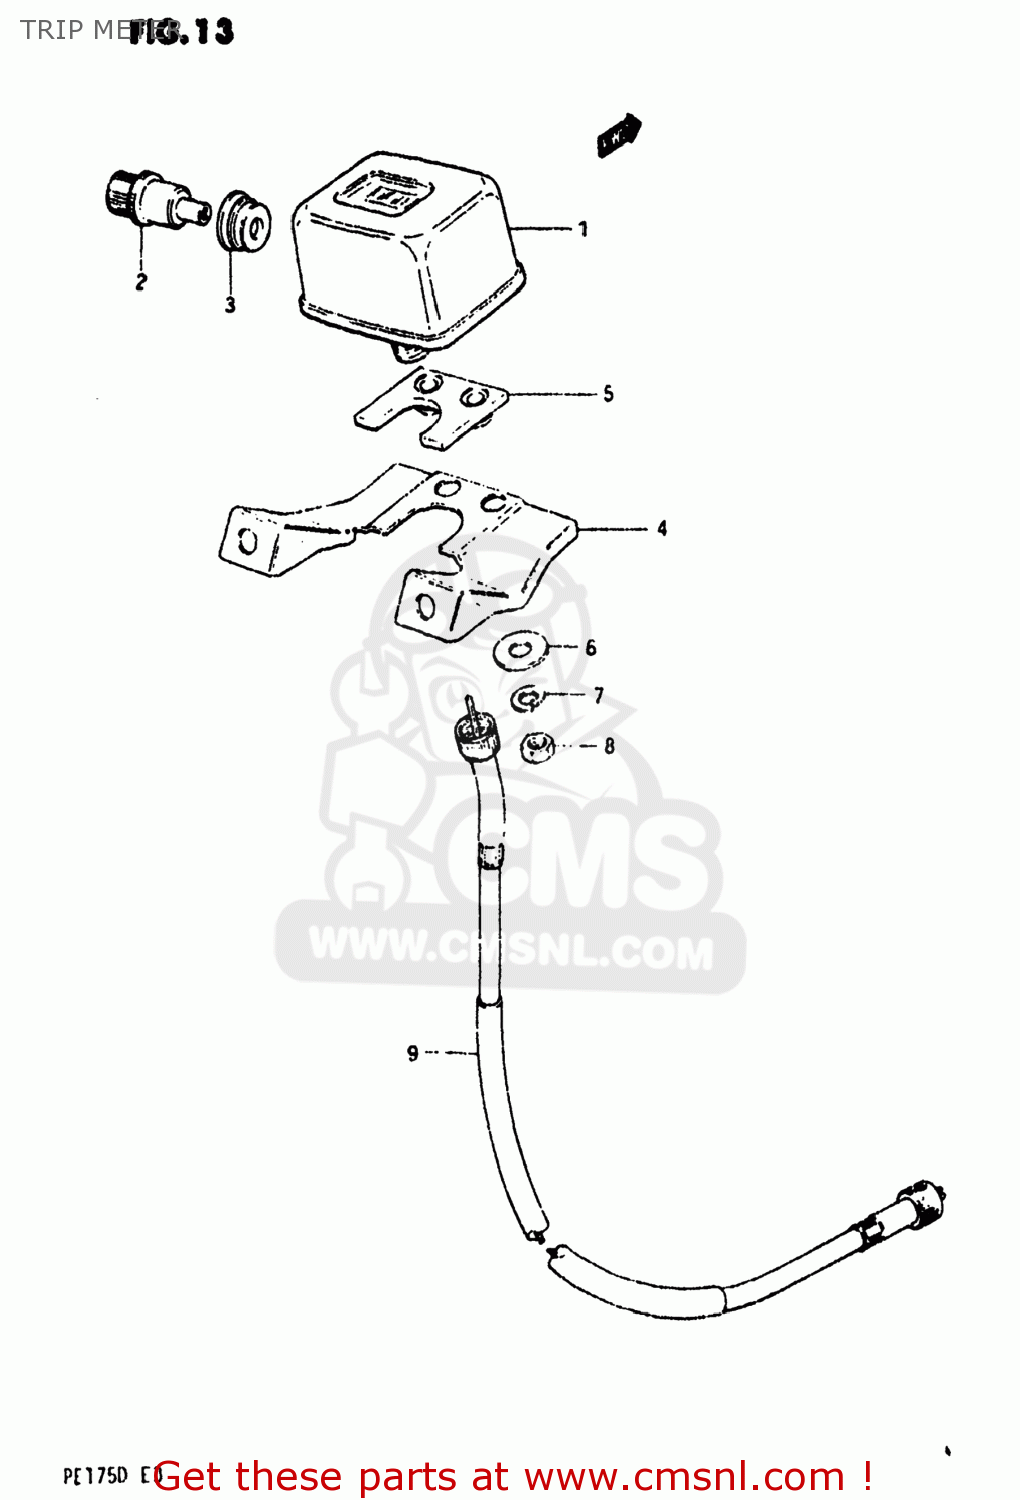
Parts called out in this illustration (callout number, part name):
1	TRIP METER
2	KNOB,TRIP METER
3	COVER,TRIPMETER KNOB
4	BRACKET,TRIPMETER
5	CUSHION,TRIPMETER
6	WASHER,METER
7	LOCK WASHER
8	NUT
9	CABLE ASSEMBLY,SPEEDOMETER
